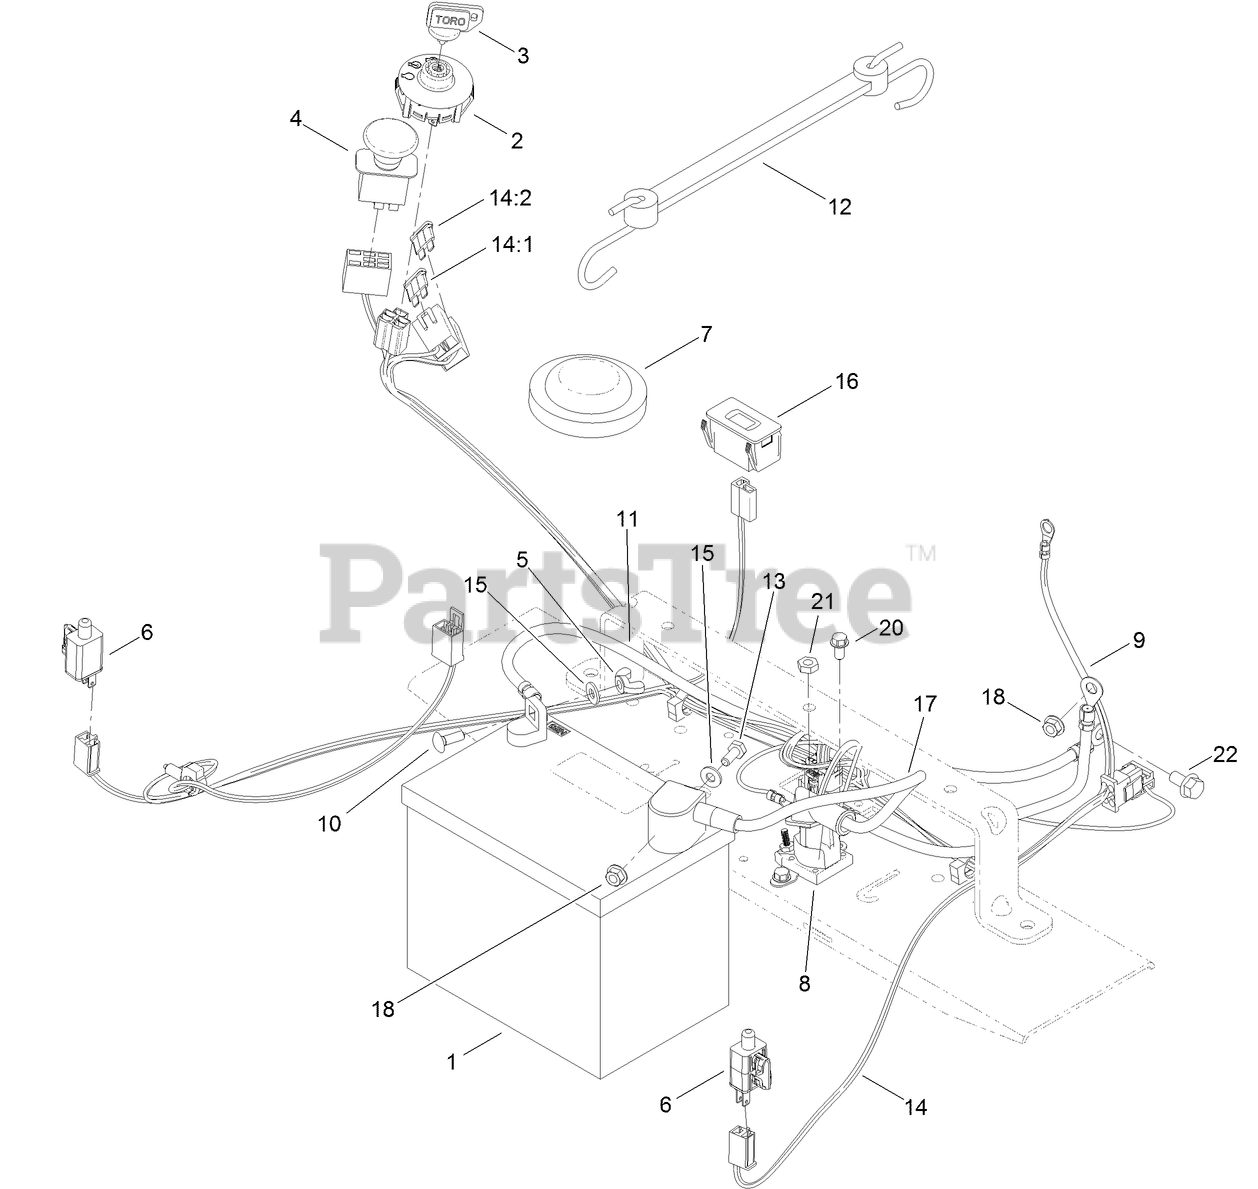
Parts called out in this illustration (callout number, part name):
1	BATTERY
3	KEY-IGNITION
4	SWITCH-PTO
5	NUT-WING
6	SWITCH
7	SWITCH-SEAT
8	SOLENOID
9	CABLE-BATTERY, RED
10	BOLT-CARR
11	CABLE-BATTERY, BLACK
12	HOLDDOWN-BATTERY
13	SCREW-HH
14:1	FUSE-BLADE, 30 AMP
14:2	FUSE-BLADE, 25 AMP
15	WASHER-FLAT
16	HOURMETER
17	CABLE-BATTERY, RED
18	NUT-HF
20	SCREW-HWH
21	NUT-JAM
22	SCREW-HHF
